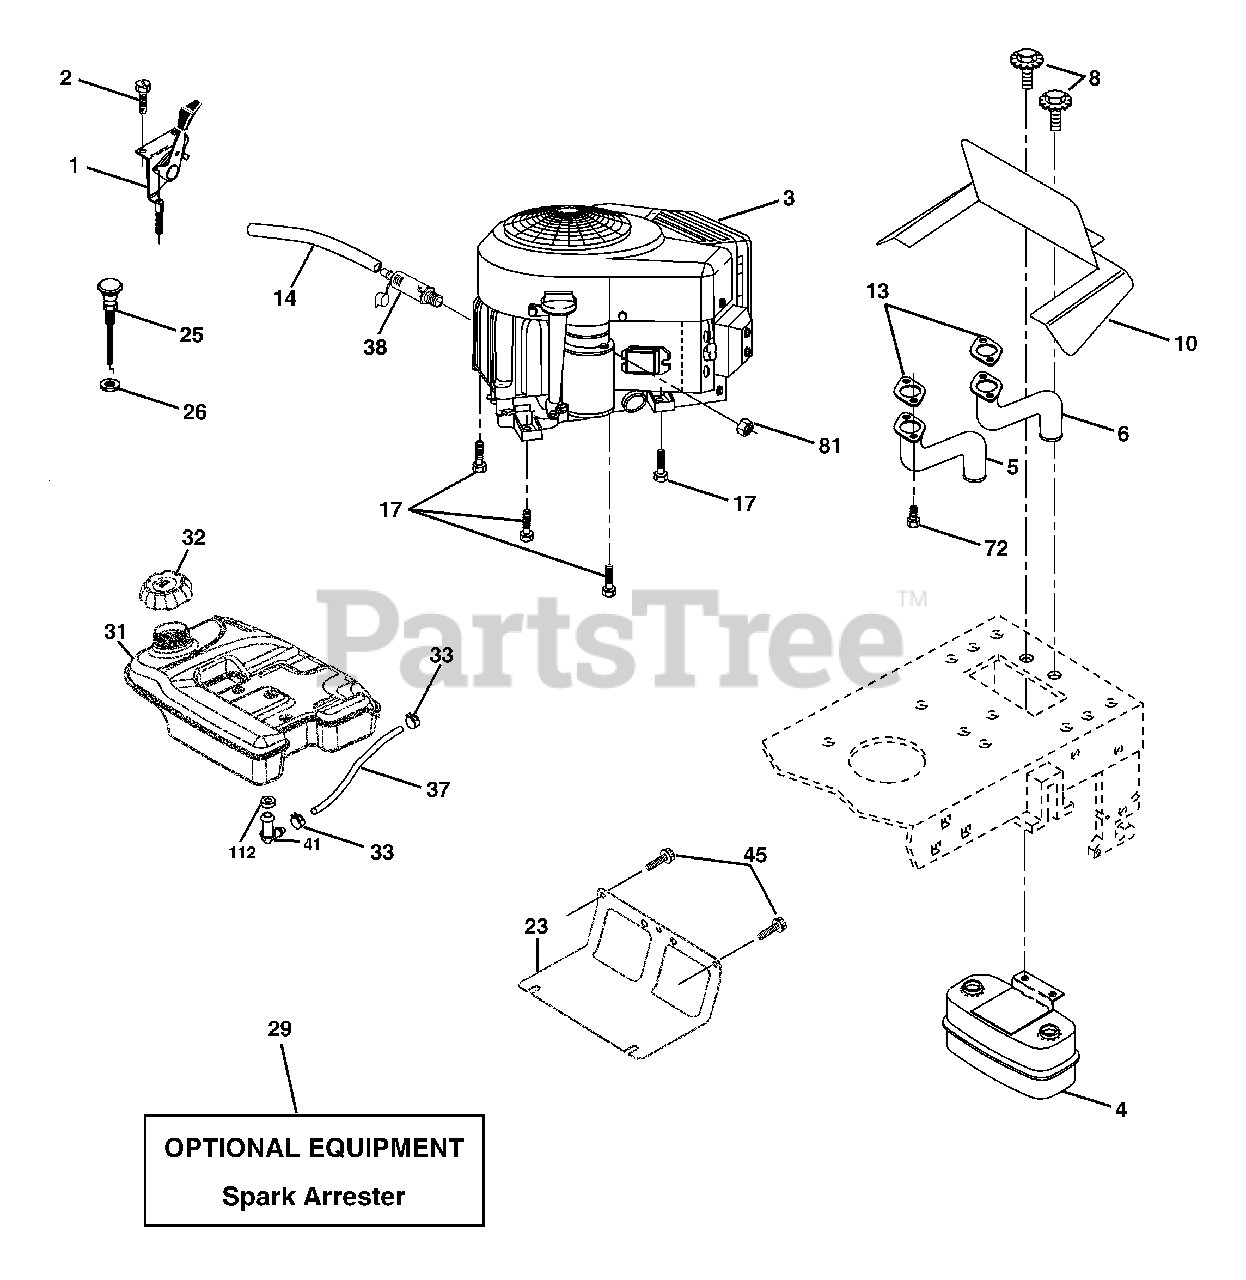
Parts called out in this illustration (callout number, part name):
1	Control, Throttle
2	Screw Hex Thd Cut 1/4-20 x 1/2
4	Muffler, Asm. Twin Lo-Tone
5	Pipe Exhaust Intek 20 RH
6	Pipe Exhaust Intek 20 LH
8	Bolt 5/16-18 unc x 3/4 w/Sems
10	Shield Browing B&S Intek II
13	Muffler Gasket
14	Tube Oil Drain
17	Screw 3/8-16 x 1-1/2
23	Shield, Browning/Debris Guard
25	Control Choke
26	Nut Keps 3/8-24 unf
29	Arrester, Spark
31	Tank, Fuel
32	Cap Gauge, Fuel
33	Clamp, Hose Blk
37	Line, Fuel
38	Plug Drain Oil Easy
41	Stem Tank Fuel
45	Screw Hex Wsh Thdrol 3/8-16 x 3/4
72	Screw Socket Head 5/16-18 x 1
81	Nut Keps Hex 1/4-20 unc
112	Bushing
